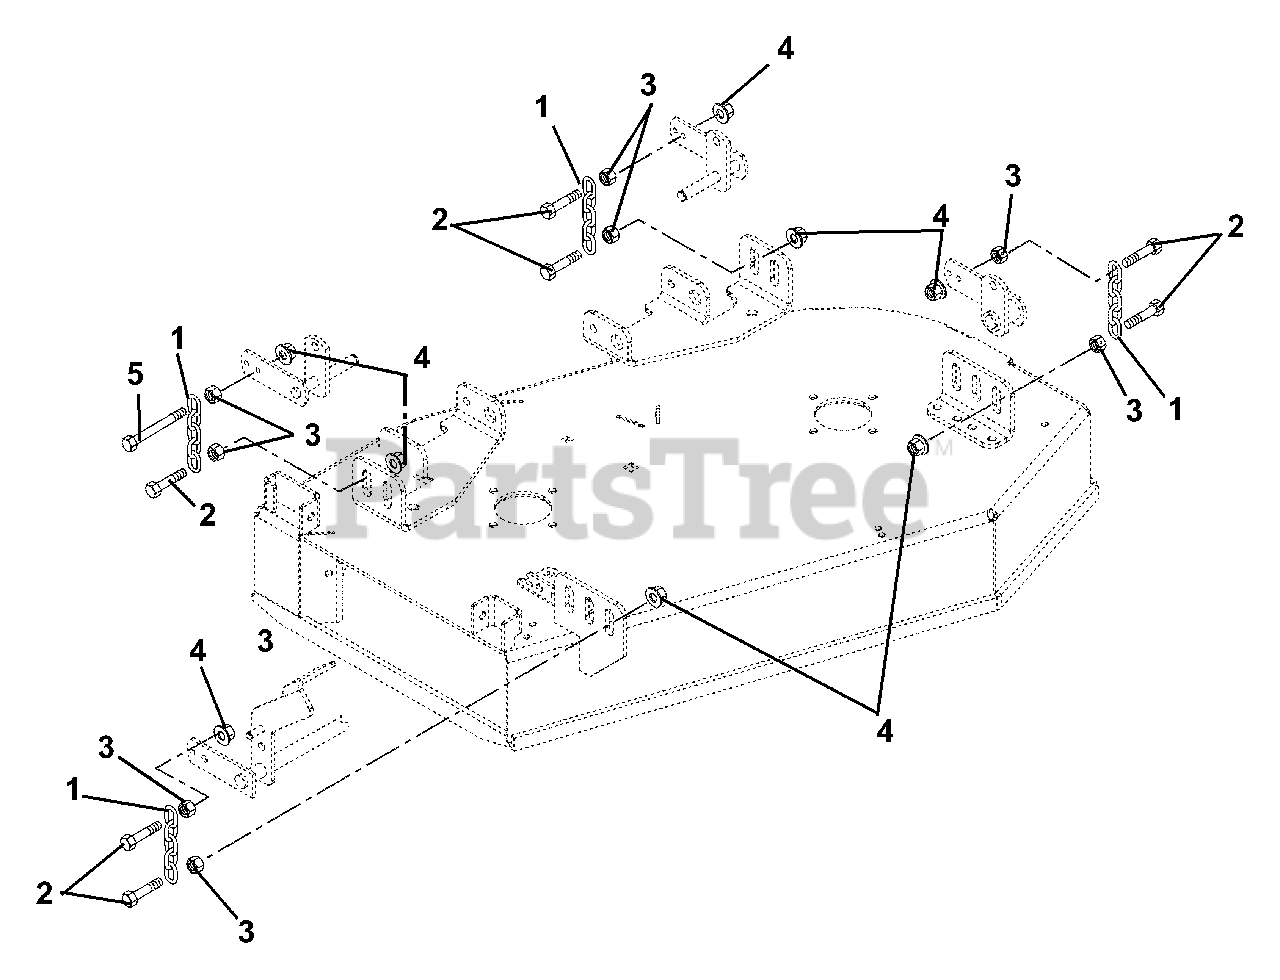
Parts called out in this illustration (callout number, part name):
1	CHAIN, LINK
2	BLT-HEX M12X1.75X55 GR5 YZ
3	NUT-SPNLK-FLG M12-1.75 YZ
4	NUT-LK-TOP-FLG M12-1.75 YZ
5	@BLT-HEX .50-13X3.00 GR5 YWZC
